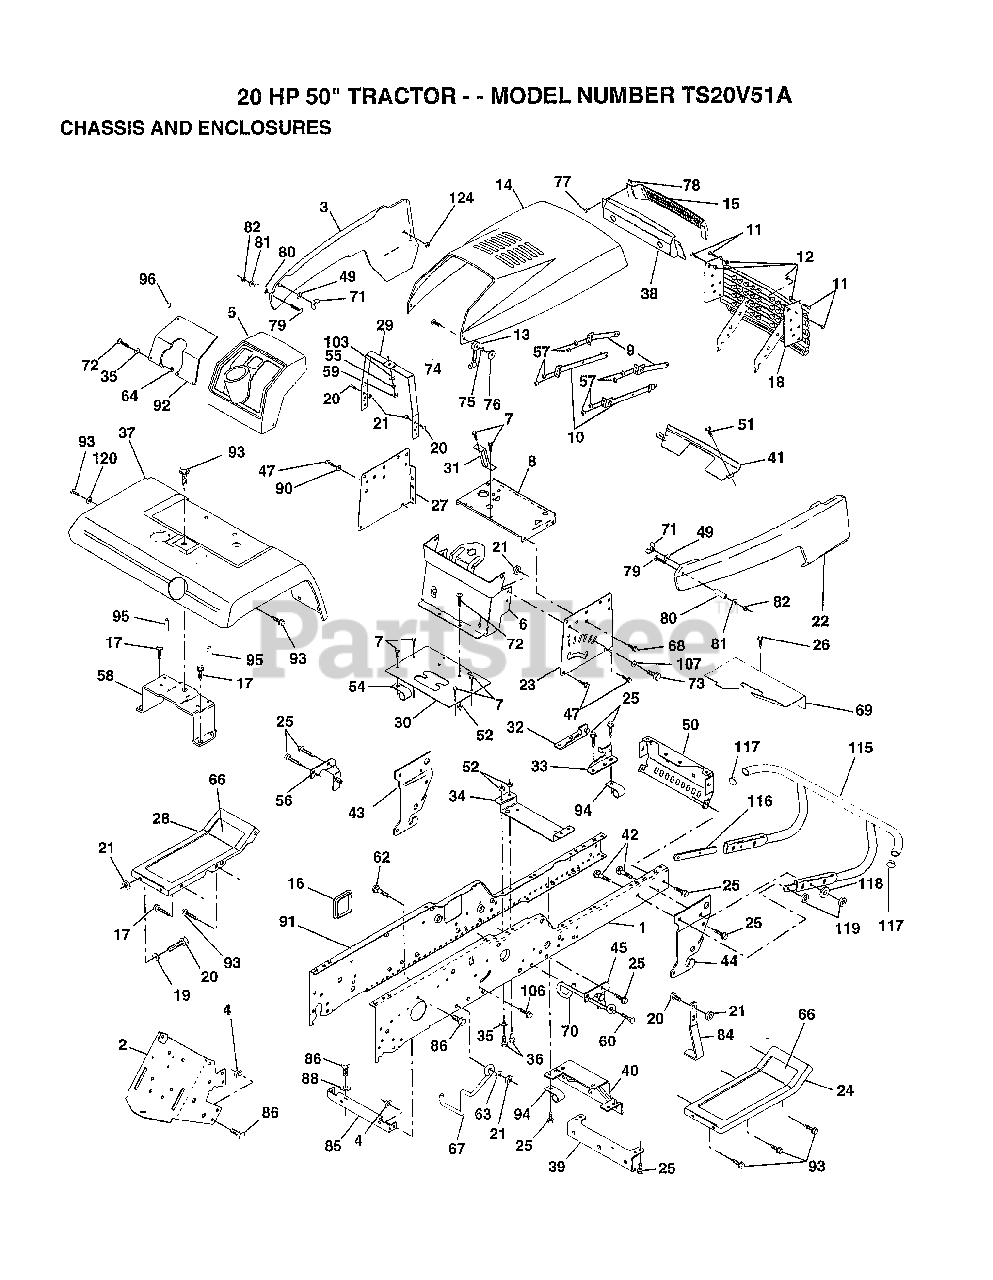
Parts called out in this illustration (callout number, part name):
2	DRAWBAR GT
4	NUT.7/16
5	DASHBOARD BLACK
6	DASH ASM LOWER
7	SCREW
8	SUPPORT BATRY VGT
12	NUT
13	HOOD LATCH T
15	LENS LT
16	COVER ACCESS
17	SCREW
18	GRILLE.ASM.PNT.YP
19	WASHER
20	BOLT
21	NUT
22	PANEL SIDE RH
25	SCREW
29	SUPPORT ASS'Y
30	SADDLE SILKSCRN
31	BRACE.SUPT.STRG
32	BRACKET ASM FRAME
33	BRACKET ASM FRAME
34	BRACKET.ENG.SUPT.
35	WASHER
36	BOLT
37	FENDER
39	BRACKET.AXLE.FRT.
41	STRAP.GRILLE.PNT.
42	BOLT.3/8-14X1.25
43	BRACKET.SUS.FT.LH
44	BRACKET.SUS.FT.RH
47	SCREW LT
50	BRACKET.CHASSIS.
51	SCREW CRT
52	NUT
54	"CLIP,INSULATOR"
55	WASHER PM
57	NUT
58	BRKT.ASM.FENDER
60	SCREW
62	BOLT D
63	WASHER
66	FOOTREST PAD
67	GUIDE BELT TRANS
68	SCREW LT
69	SHIELD.HEAT.VGT.
70	GUIDE.BELT.MID.SP
72	SCREW
73	BOLT
74	SCREW
75	LOCKWASHER
76	WELDNUT
78	"""J"" FASTENER LT"
79	SCREW
80	SPACER LT
81	WASHER
84	STOP.OVER.CENTER
86	BOLT
88	LOCKWASHER
90	LOCKWASHER
92	PLATE YP SLKSCR
93	SCREW LT
94	CLIP GTV
95	NUT-PUSH YT
96	PLUG-DASH T
103	LOCKWASHER
107	WASHER
115	BUMPER.ASM.W/PY
116	BRACKET.EXT.BUMP.
117	PLUG.PLASTIC
118	WASHER
119	NUT
120	WASHER HYT
